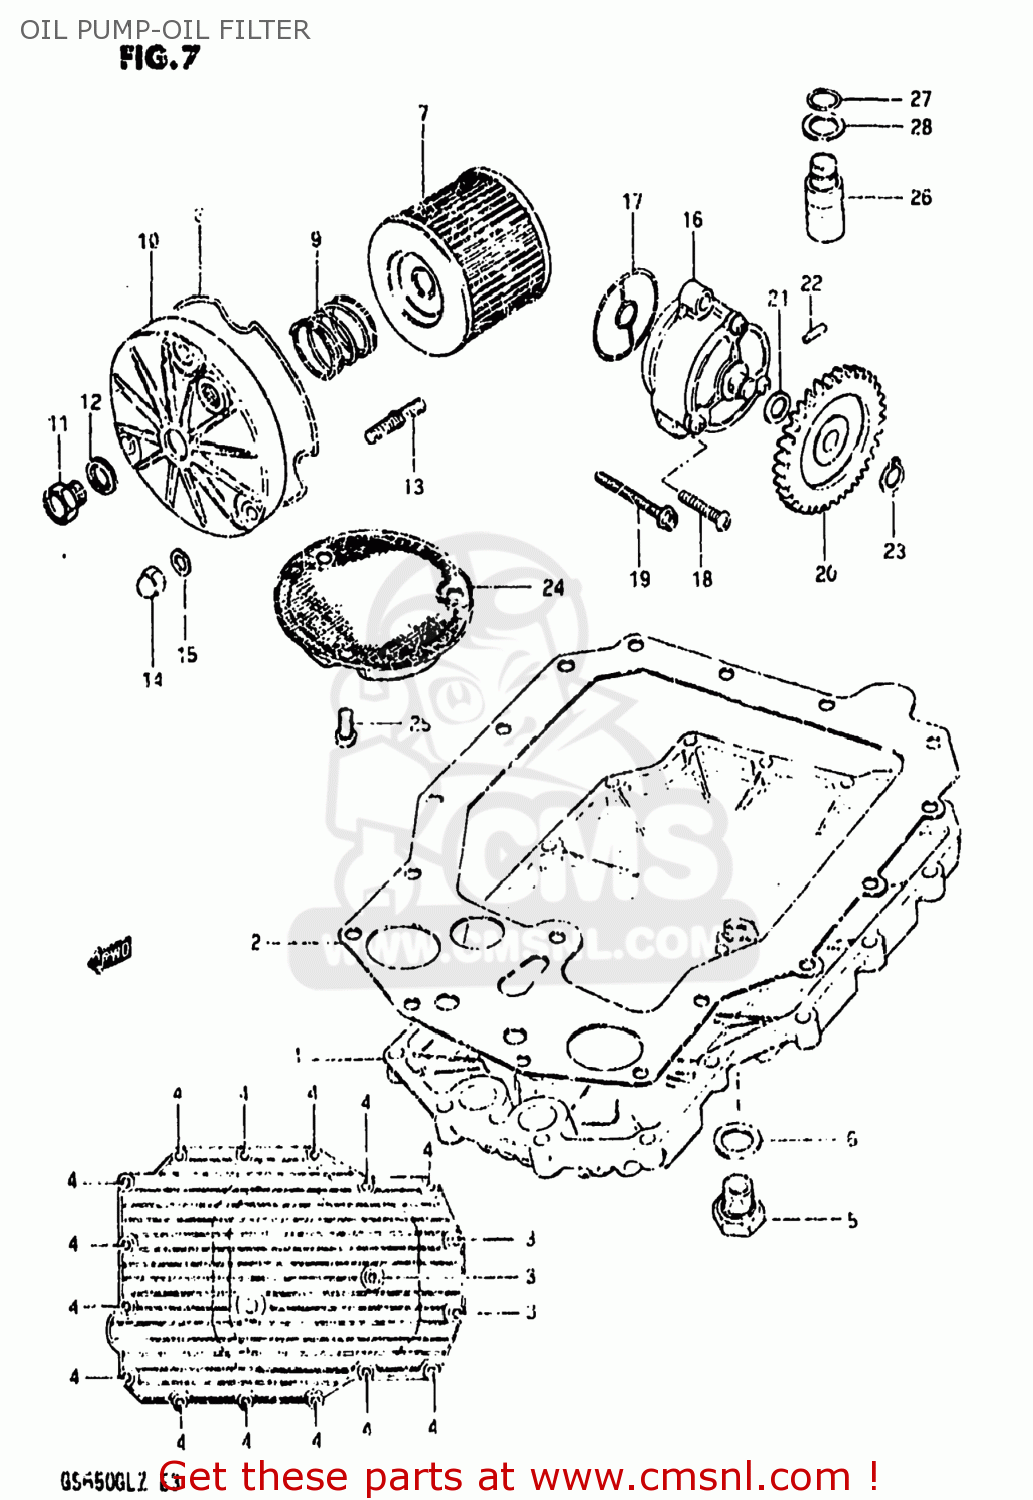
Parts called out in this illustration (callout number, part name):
1	PAN,OIL
2	GASKET,OIL PAN (MCA)
3	BOLT
4	BOLT
5	PLUG
6	GASKET(14X19.2X2) (NAS)
7	FILTER ASSY,ENGINE OIL
8	O RING,OIL FILTER CHAMBER CAP
9	SPRING
10	CAP,OIL FILTER
11	PLUG
12	GASKET(14X19.2X2) (NAS)
13	STUD 6X20
14	NUT
15	WASHER
16	PUMP ASSEMBLY,OIL
17	O-RING,OIL PUMP
18	SCREW
19	BOLT
20	GEAR,OIL PUMP DRIVEN
21	SHIM
22	PIN(4X15.8)
23	CIRCLIP
24	STRAINER,ENGINE OIL
25	SCREW 6X12
26	REGULATOR ASSEMBLY,ENGINE
27	O-RING
28	WASHER
